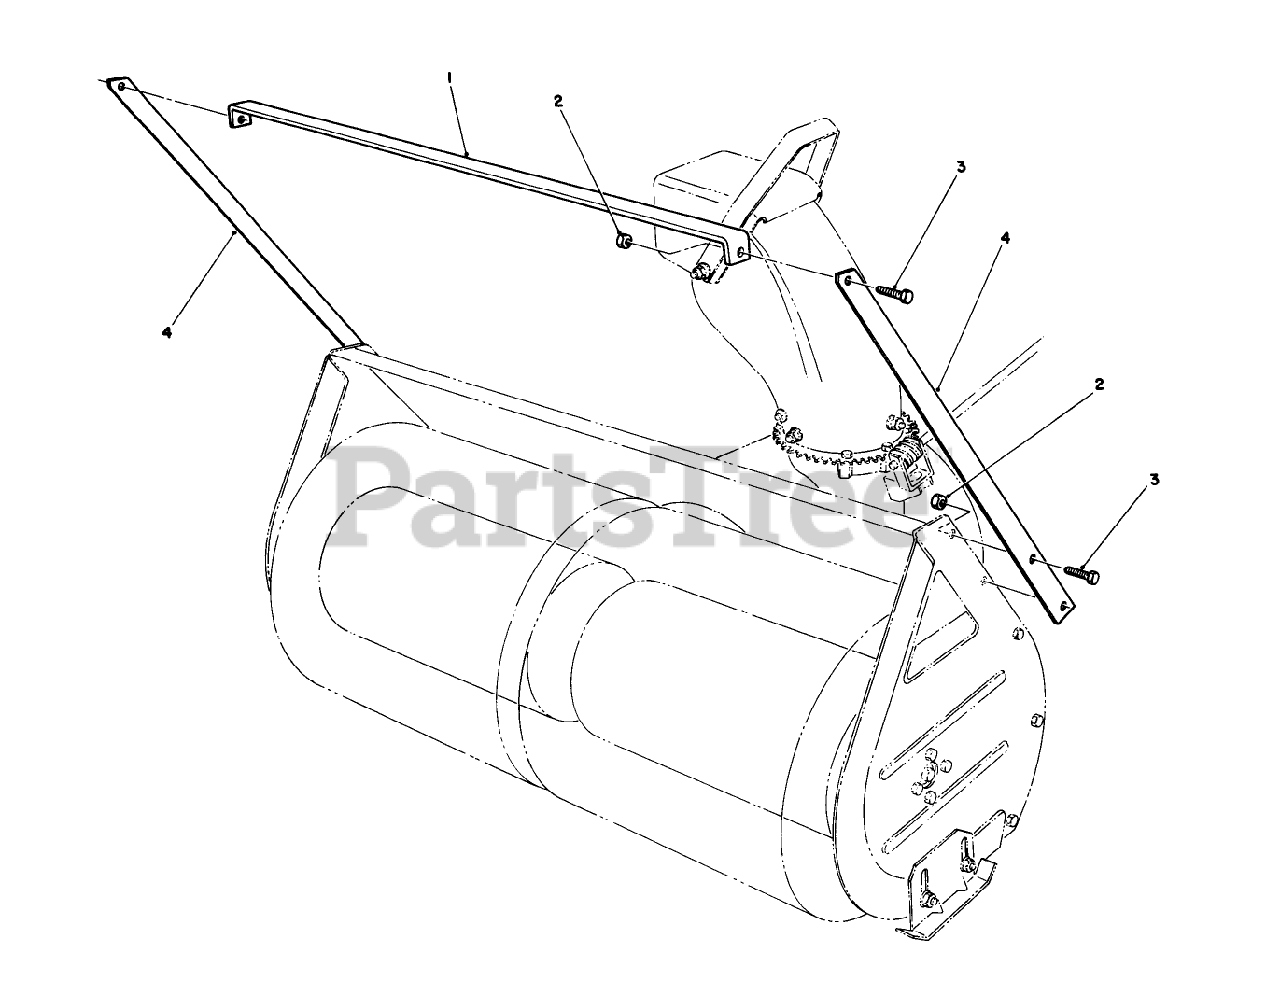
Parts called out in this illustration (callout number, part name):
1	32 TOP DRIFT BREAKER
2	NUT-LOCK, CONE
3	SCREW-HH
4	SIDE DRIFT BREAKER
